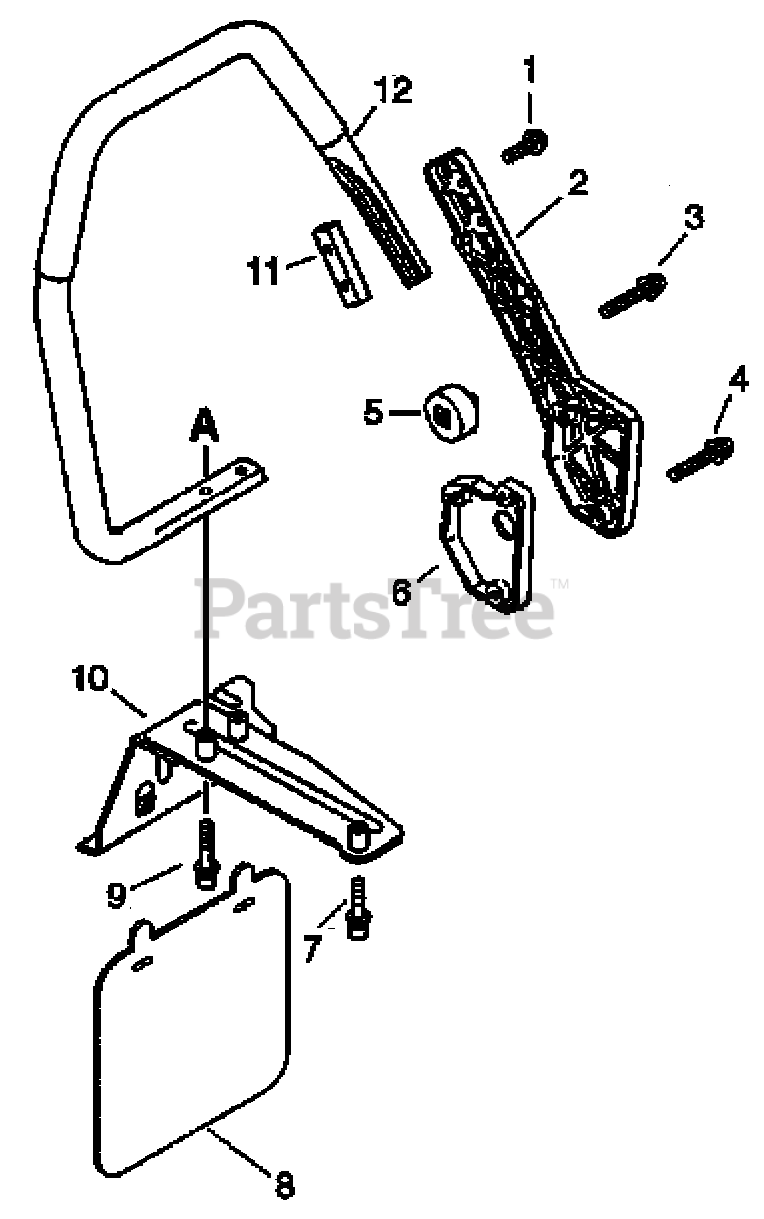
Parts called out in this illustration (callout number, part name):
1	SCREW 5×20
2	BRACKET, HANDLE
3	SCREW 5×30
4	SCREW 5×35
7	BOLT 5×30
9	BOLT M5×35
10	FIXTURE,HANDLE
12	HANDLE, FRONT
